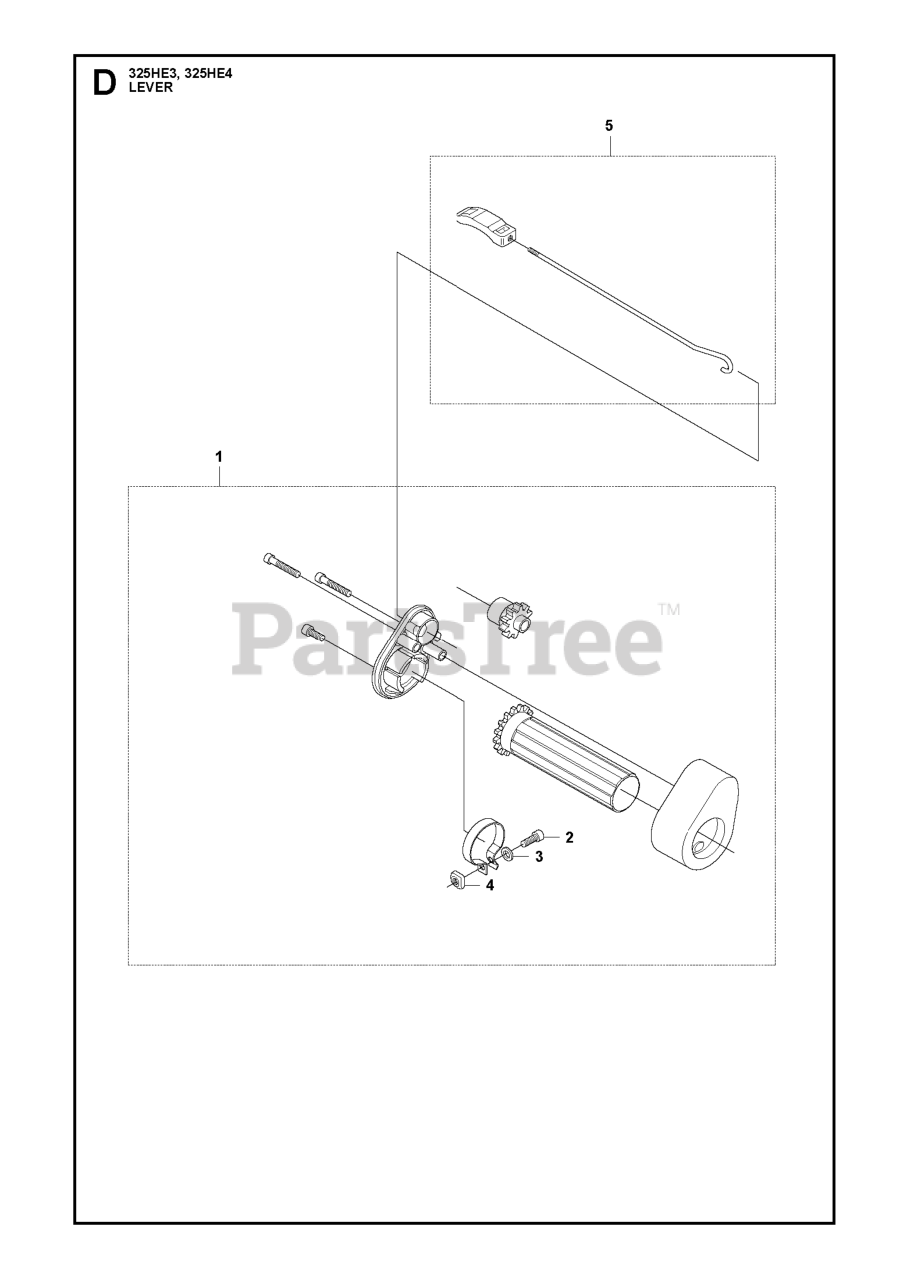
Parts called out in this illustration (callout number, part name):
2	SCREW MC6S 5X16
3	WASHER
4	SQUARE NUT M5
